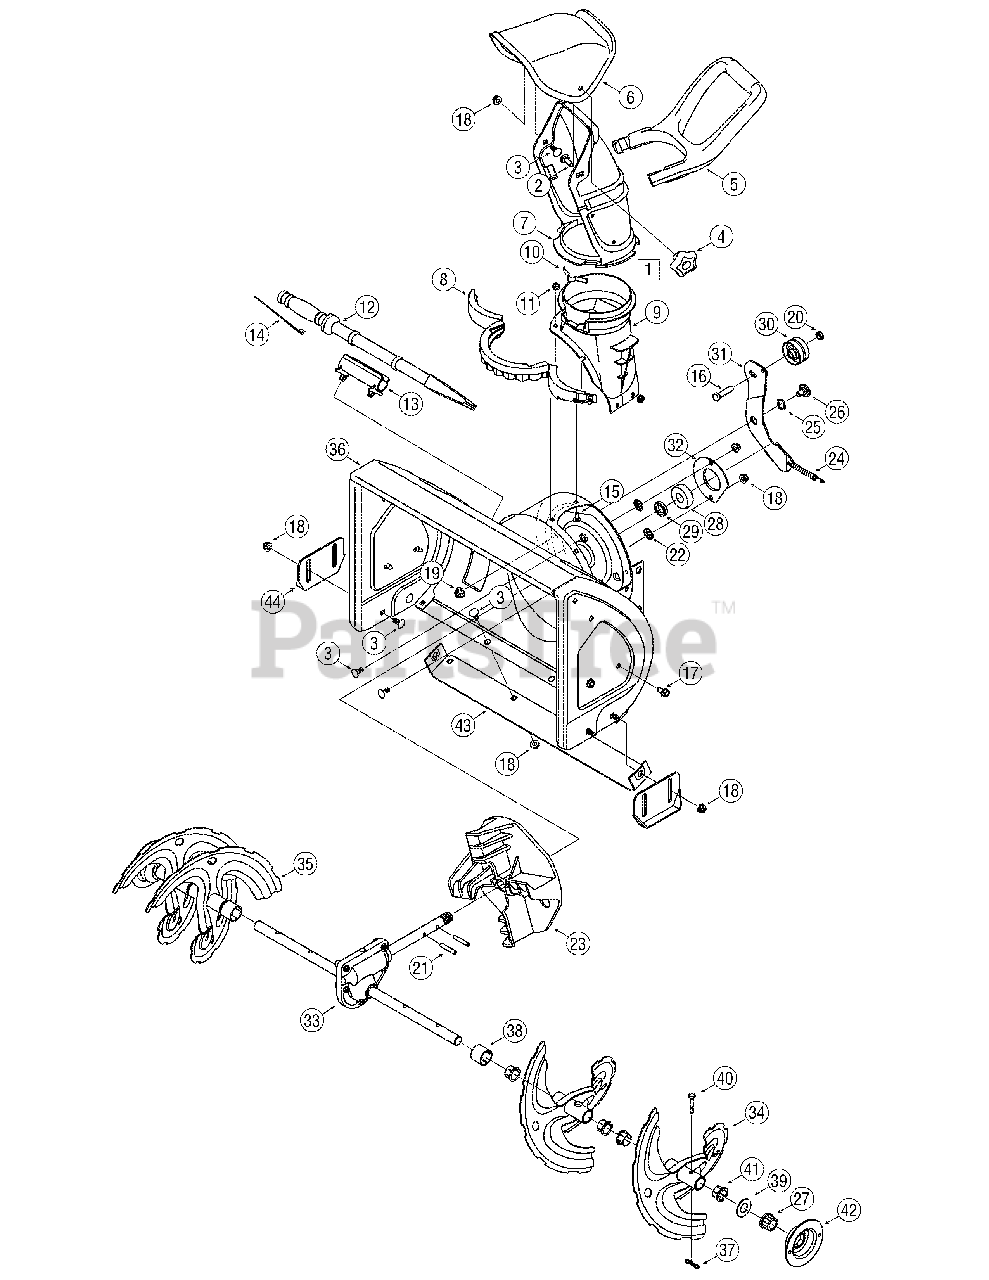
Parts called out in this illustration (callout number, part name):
1	Chute Assembly
2	Carriage Bolt 5/16-18 x 1
3	Carriage Bolt 5/16-18
4	Star Knob 5/16-18 (black)
4	Star Knob 5/16-18 (yellow)
5	Chute Handle
6	Upper Chute
7	Lower Chute
8	Chute Ring
9	Chute Adapter 5" Dia.
10	Chute Adjustment Spring
11	Flange Lock Nut 1/4-20
12	Clean-out Tool
13	Clean-out Tool Mount
14	Cable Tie
15	Carriage Screw 1/4-20 x .62
16	Hex Bolt 3/8-16 x 1.50
17	AB Screw 5/16-18 x .625
18	Flange Lock Nut 5/16-18
19	Flange Lock Nut 3/8-16
20	Hex Lock Nut 3/8-16
21	Spiral Pin
22	Push On Nut
23	Impeller
24	Extension Spring
25	Wave Washer
26	Shoulder Screw 3/8-16
27	Hex Flange Bearing
28	Ball Bearing
29	Spacer
30	Flat Idler
32	Bearing Housing
33	Auger Gearbox Assembly
37	Bow Tie Cotter Pin 72
38	Spacer 1.25 x .75 x 1.00
39	Flat Washer
40	Shear Pin .25 x 1.50
41	Flange Bushing
